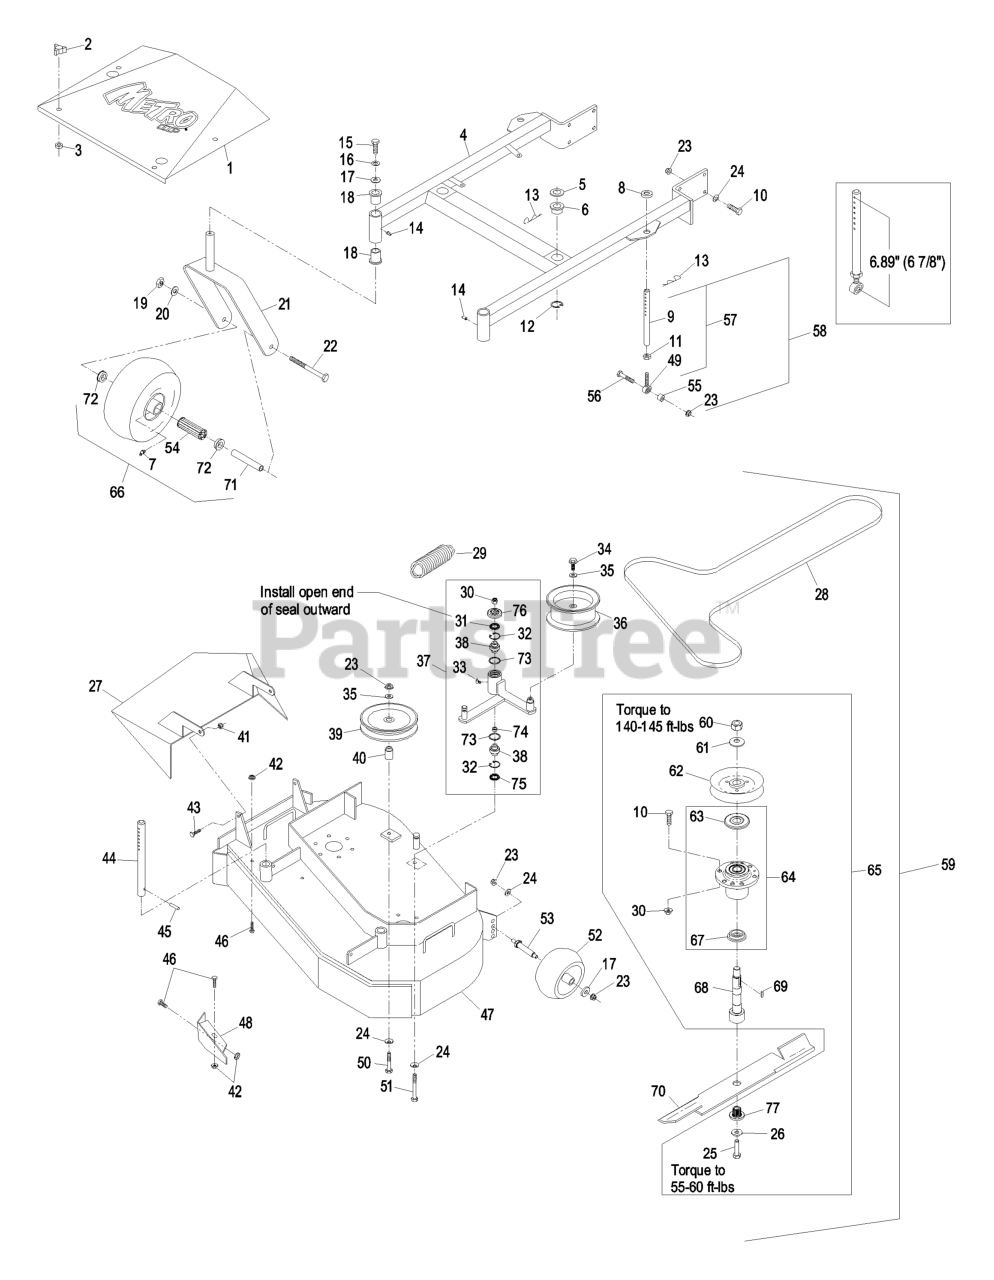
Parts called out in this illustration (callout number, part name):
1	SHIELD W/DECAL,MHP36
2	KNOB-3 PRONG
4	DECK SUPPORT W/BSHGS 36"
5	SPACER-DECK SUPPORT
6	BUSHING-DECK
7	FITTING-GREASE
9	LINK,SUPPORT
10	SCREW-HH
11	NUT-HEX
12	RING-RETAINING
13	PIN,HAIR COTTER
14	FITTING-GREASE
15	SCREW-HH
16	WASHER-LOCK
18	BEARING-FLANGED
19	NUT-HH
20	WASHER-LOCK
22	SCREW-HH
23	NUT-HHF, WHIZ
24	WASHER-BELLEVILLE
25	SCREW-HH
26	WASHER-SPRING
27	WLD,DISCHARGE CHUTE 36/48
28	BELT,DECK DRIVE
30	NUT-LOCK, NI
31	SEAL-LIP, SINGLE
32	RING-SNAP
33	FITTING-GREASE, 90 DEG
34	SCREW-HHF
35	WASHER-FLAT
37	KIT, DECK IDLER TTHP 36"(
38	BEARING-SPHERICAL
39	PULLEY-IDLER
40	BUSHING-IDLER
41	NUT-LOCK, NI
43	SCREW-HH
44	ROD,DECK SUPPORT
46	SCREW-HH
47	ASM,DECK W/DECALS TTHP/MH
49	BALLJOINT
50	SCREW-HH
51	SCREW-HH
52	ROLLER-SCALP, ANTI
54	BEARING
56	SCREW-HH
59	Asm, Deck Complete
60	NUT-HH
62	SHEAVE,W/HUB 5.72
63	GUARD-BEARING, TOP
64	KIT, CUTTER HOUSING
65	ASM, CUTTER HSG
66	KIT, SP CASTER WHEEL REPL
67	SPACER-GUARD, BOTTOM
68	KIT, SPLINED SPINDLE 103-
69	KEY-RECTANGLE
72	BUSHING
75	SEAL-LIP, DOUBLE
76	GUARD-TOP
77	BUSHING,SPLINED
